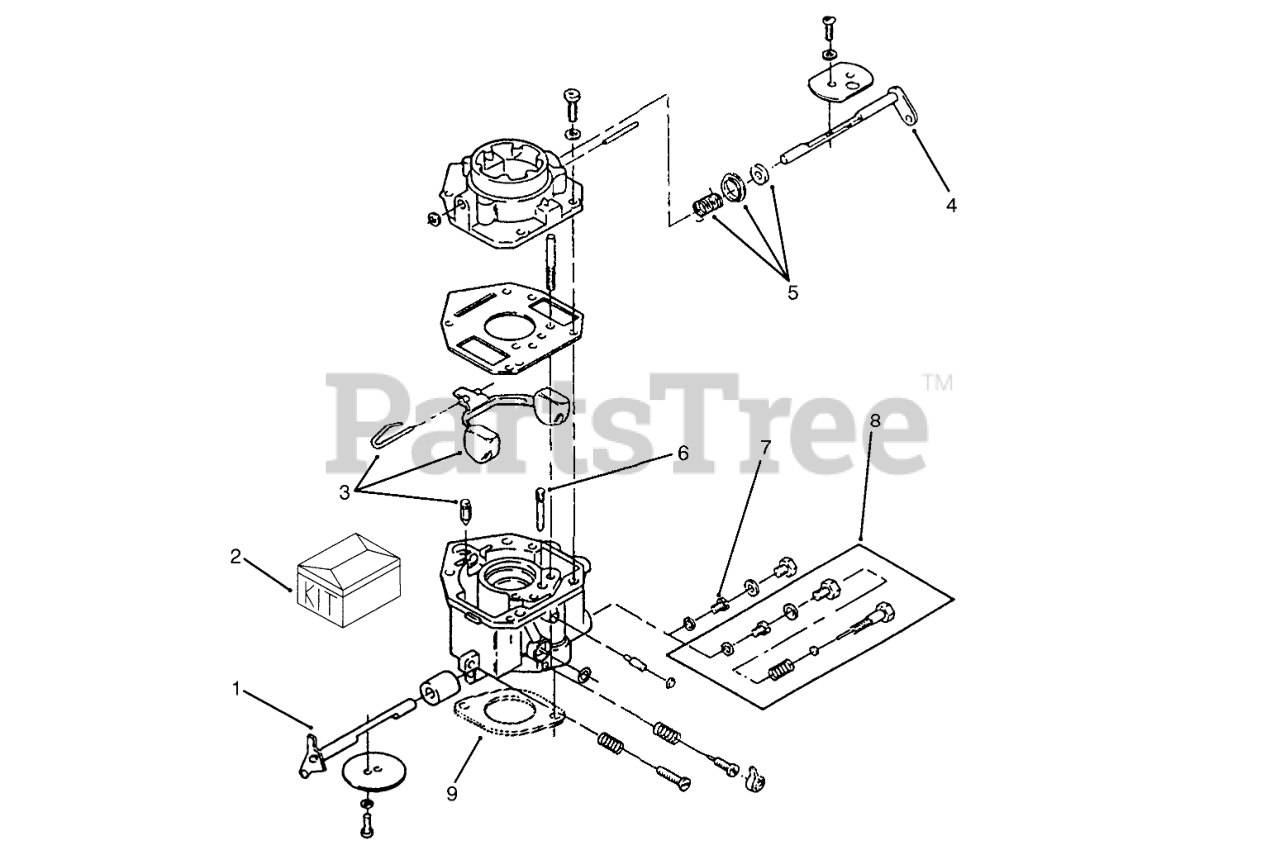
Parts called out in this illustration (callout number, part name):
1	Kit-Shaft, Throttle (Includes Valve Setscrew, Air Filter, & Throttle Valve)
2	Kit-Repair (Includes Screw & Plug Package, Gasket Package, Float Valve, Idle Adj. Needle & Spring, Mounting Gaskets, & Idle Limit Cap)
3	Kit-Float (Includes Float, Pin & Valve)
4	Kit-Shaft, Choke (Incl. Choke Valve, Valve Setscrew, & Air Filter)
5	Kit-Lever, Choke (Incl. Choke Lever Ring, Choke Spring, & Choke Collar)
6	IDLE-JET
7	POWER JET
8	FIXED-JET
9	GASKET-CARBURETOR
